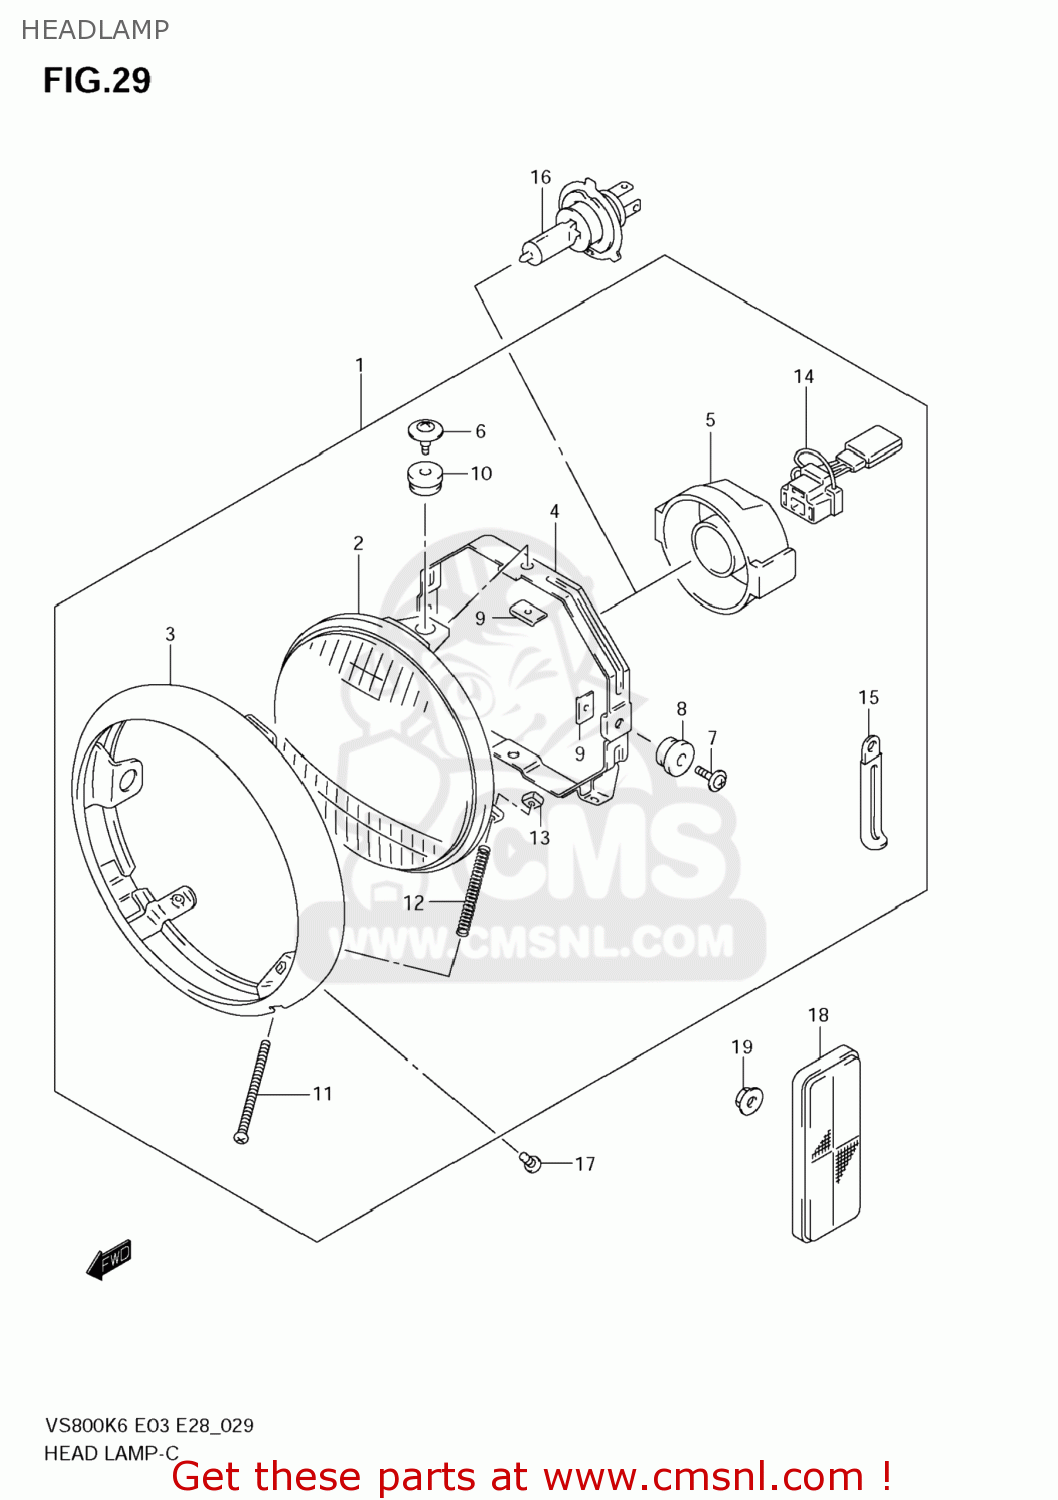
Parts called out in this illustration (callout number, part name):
1	HEADLAMP ASSY
2	UNIT,LAMP
3	RIM
4	RING,MOUNTING
5	COVER
6	SCREW
7	SCREW,MOUNTING
8	CUSHION
9	NUT
10	CUSHION
11	SCREW,ADJUSTING(4X50)
12	SPRING
13	NUT,HEADLAMP ADJUST
14	SOCKET
15	CLAMP(L:65)
16	BULB(12V60/55W,H4)
17	SCREW
18	REFLEX REFLECTOR,FR SIDE
19	NUT
